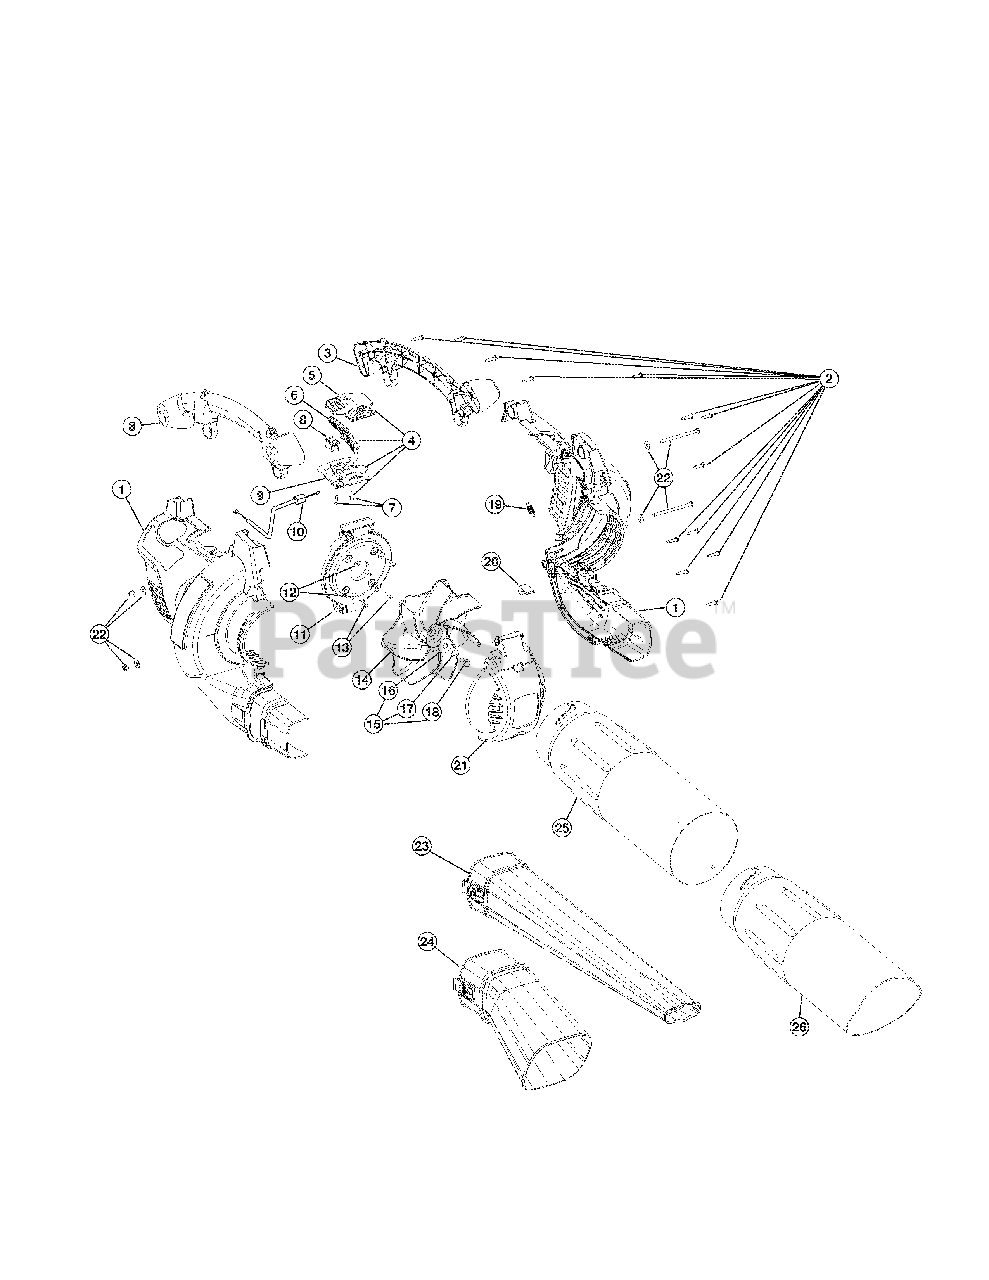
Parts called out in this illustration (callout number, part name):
1	Engine Cover Assm (includes 2)
3	Handle Assm (includes 2)
4	Throttle control Assm (includes 5-7 & 9)
5	Upper Throttle Control Plate
6	Throttle Control Lever
8	Rocker Switch Assm
9	Lower Throttle Control Plate
10	Throttle Cable
11	Engine Mount Plate (includes 12 & 13)
14	Impeller Blade
15	Impeller Hardware (includes 16-18)
16	Washer
17	Lock Washer
19	Vacuum Door Spring
20	Vacuum Door Lock
21	Vacuum Door
22	Mounting Plate Hardware
23	Blower Tube
24	Vacuum Bag Adaptor
25	Upper Vacuum Tube
26	Lower Vacuum Tube
